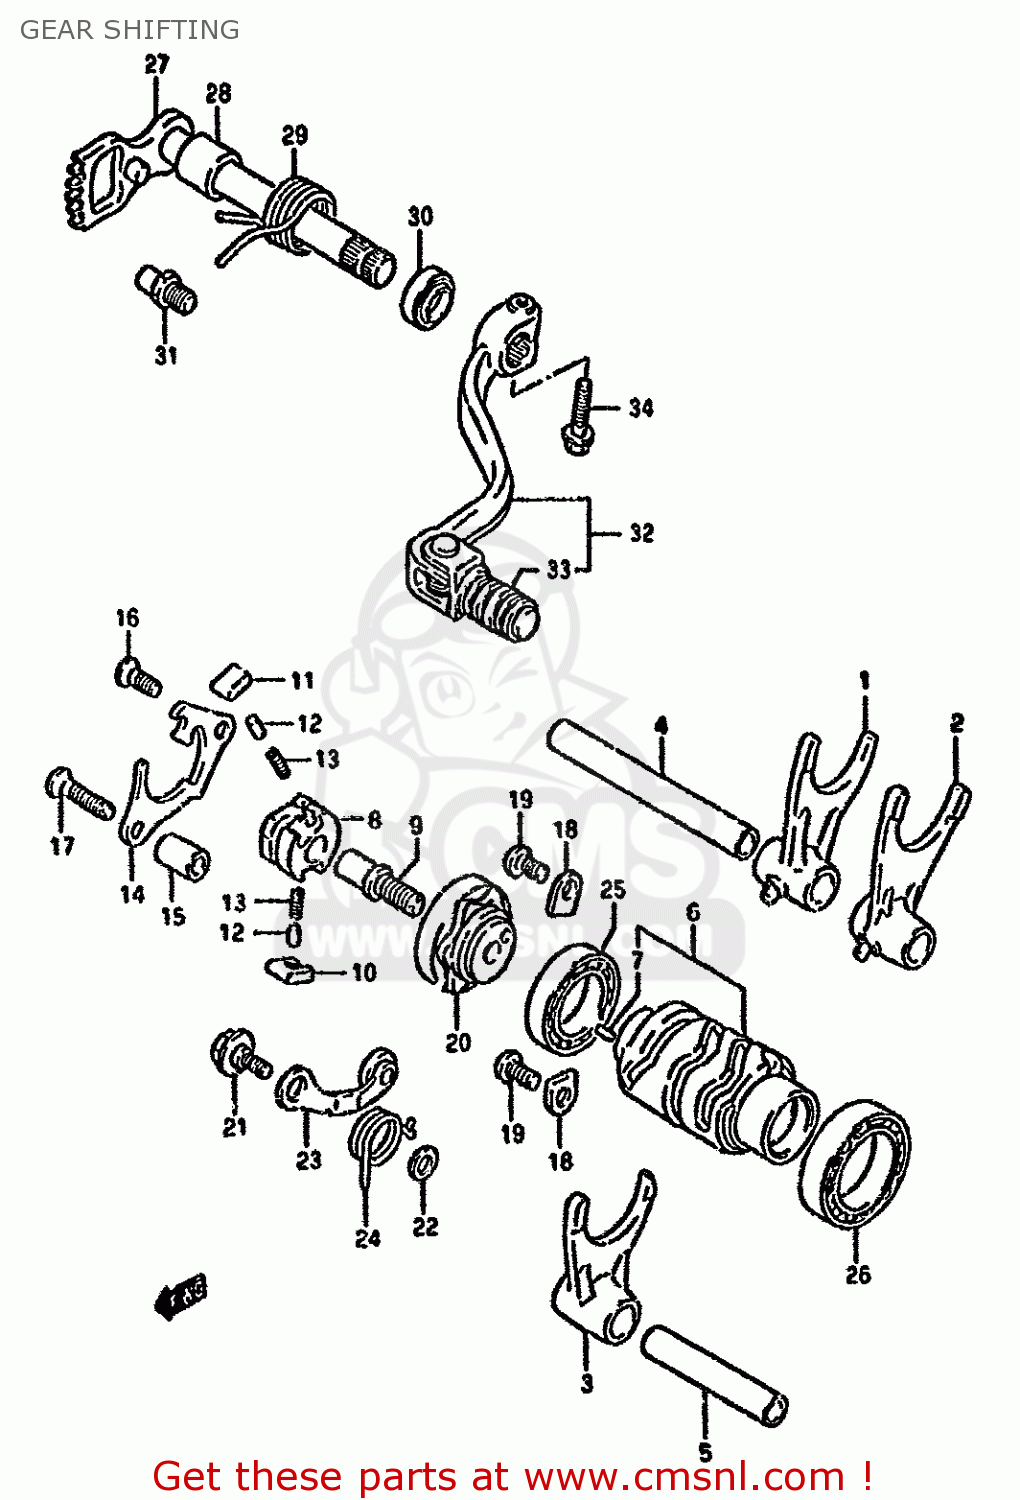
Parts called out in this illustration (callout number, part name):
1	FORK,GEAR SHIFT NO.1
2	FORK,GEAR SHIFT NO.2
3	FORK,GEAR SHIFT NO.3
4	SHAFT,GEAR SHIFT FORK
5	SHAFT,GEAR SHIFT FORK
6	CAM COMP,GEAR SHIFT
7	PIN
8	GEAR,GEARSHIFT CAM DRIVE
9	PIN,SHIFT CAM DRIVEN GEAR
10	PAWL,GEAR SHIFT NO.1
11	PAWL,GEAR SHIFT NO.2
12	PIN(5X8)
13	SPRING
14	LIFTER,GEAR SHIFT POLE
15	SPACER(6.2X12X18)
16	SCREW
17	SCREW
18	RETAINER
19	SCREW 6X12
20	PLATE,SHIFT CAM STOPPER
21	BOLT(6X14.3)
22	WASHER
23	STOPPER,SHIFT CAM
24	SPRING
25	BEARING
26	BEARING(30X37X12)
27	SHAFT,GEAR SHIFT
28	SPACER(14X20X17.5)
29	SPRING
30	SEAL,OIL(14X22X6)
31	STOPPER,GEAR SHIFT CAM
32	LEVER ASSY,GEAR SHIFT
33	RUBBER,GEAR SHIFT PEDAL
34	BOLT
